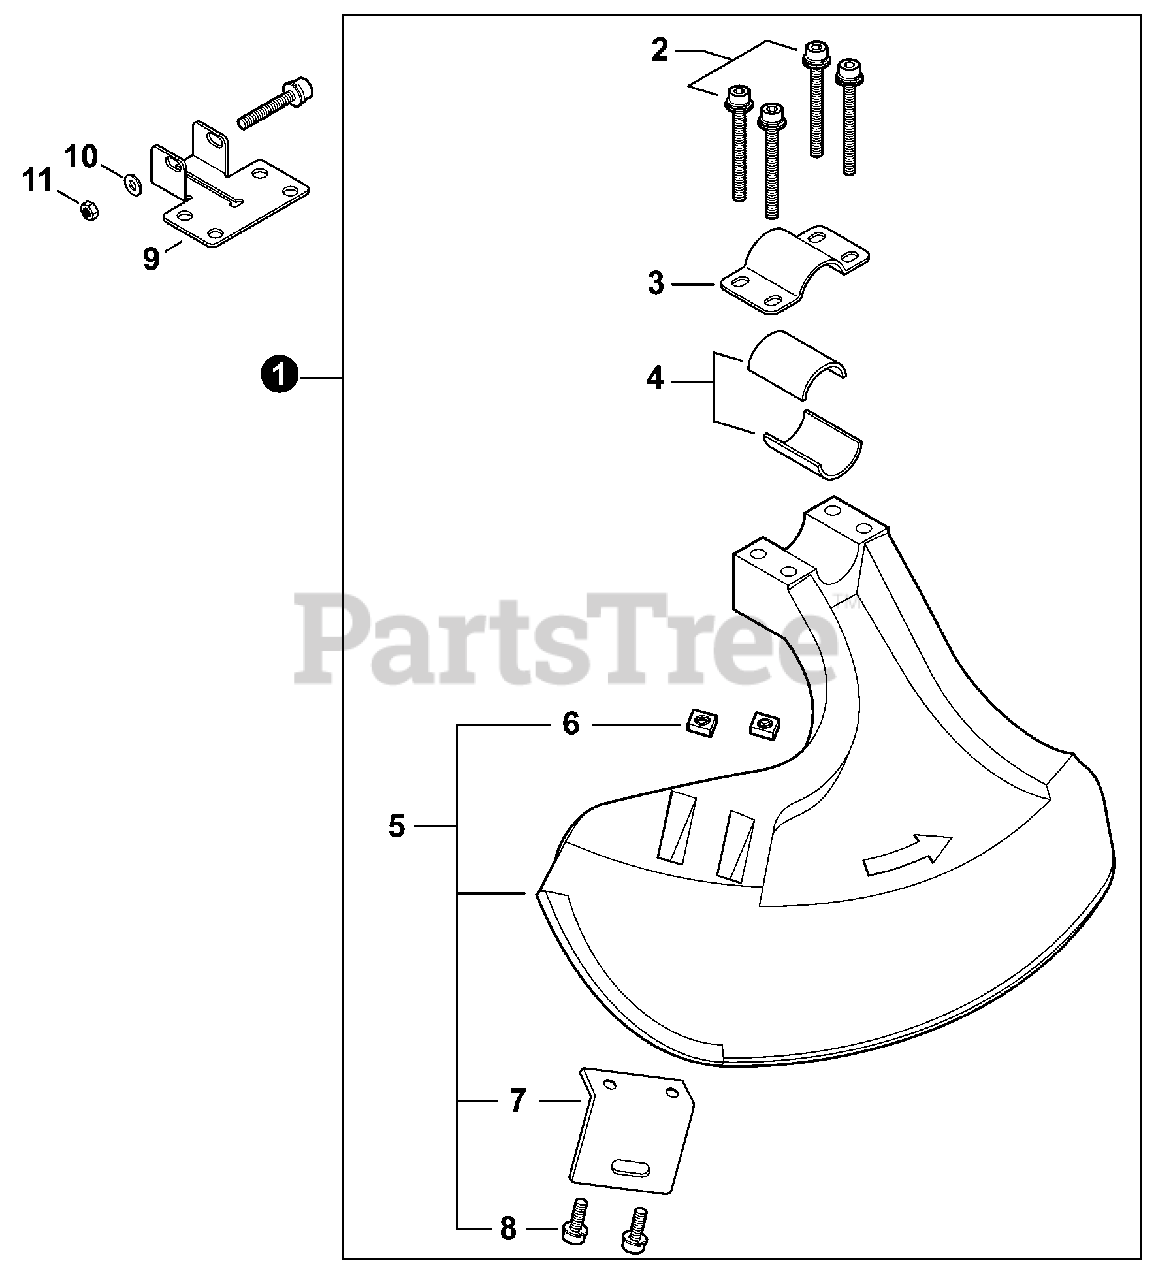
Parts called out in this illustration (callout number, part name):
1	DEBRIS SHIELD KIT
2	BOLT M5×45
3	CLAMP, UPPER
4	SPACER 24
5	DEBRIS SHIELD ASSY
8	BOLT M5×16
9	PLATE, SHIELD MOUNTING
10	WASHER 5.5×12×0.8
11	NUT M5
